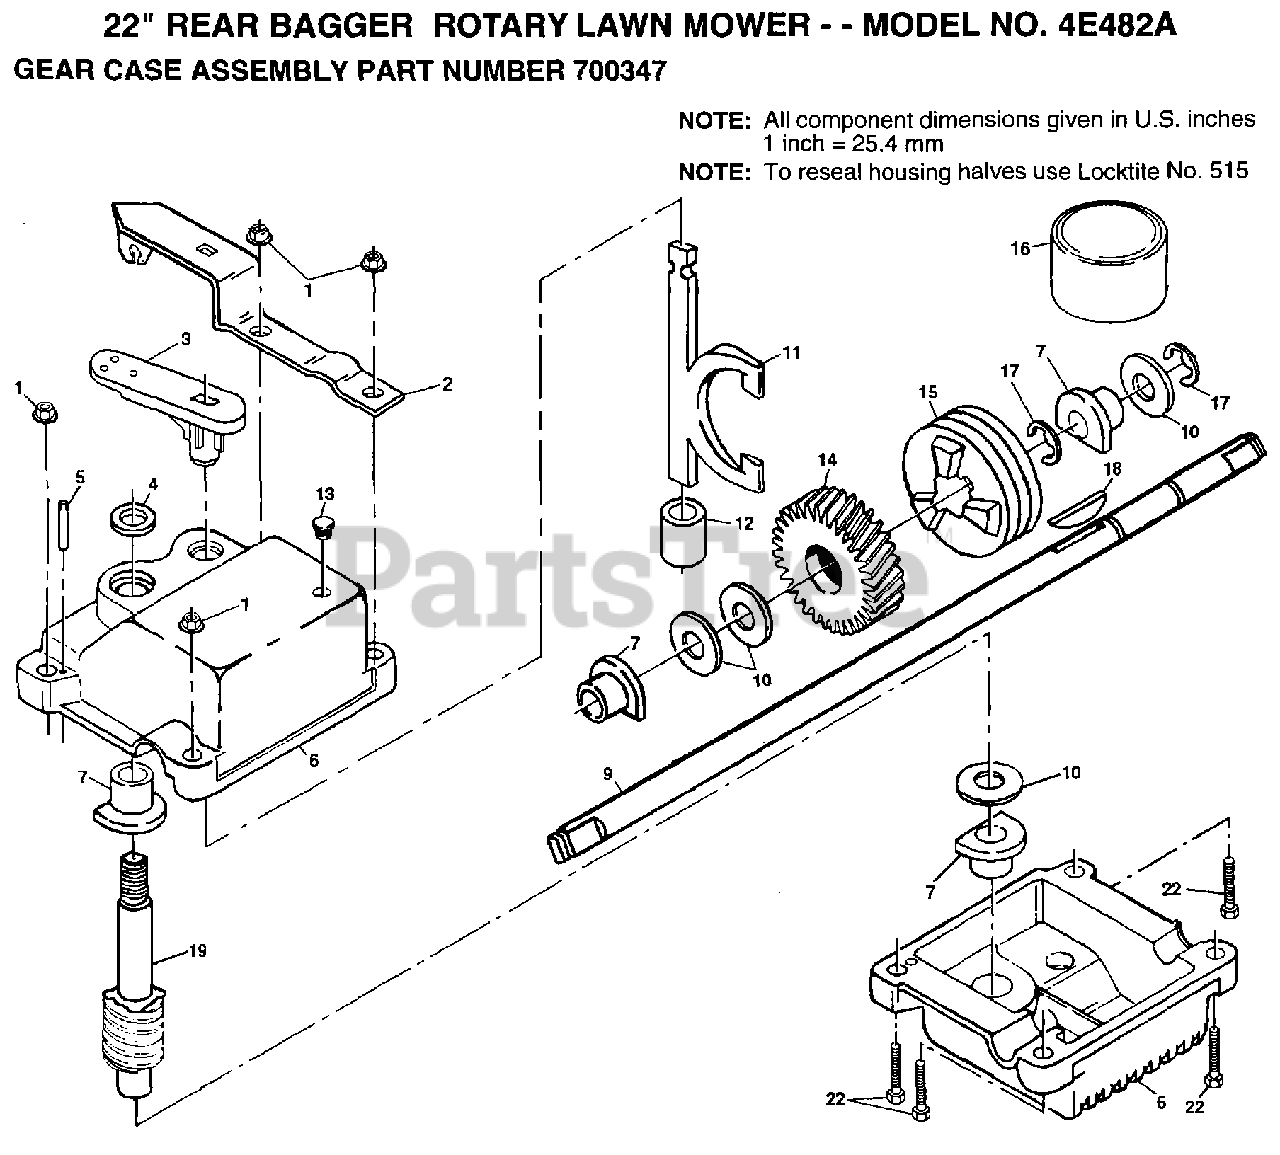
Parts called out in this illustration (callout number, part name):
1	NUT
3	SHIFTER
4	SEAL
5	DRIVE LOK PIN
6	GEARCASE KIT
7	BEARING
9	SHAFT.DRIVE
10	THRUST WASHER
11	CLUTCH YOKE
12	BUSHING.GEAR BOX
13	PLUG PM
14	GEAR.HELICAL
15	CLUTCH JAW
17	RING T
18	HI PRO KEY
19	SHAFT.WORM
